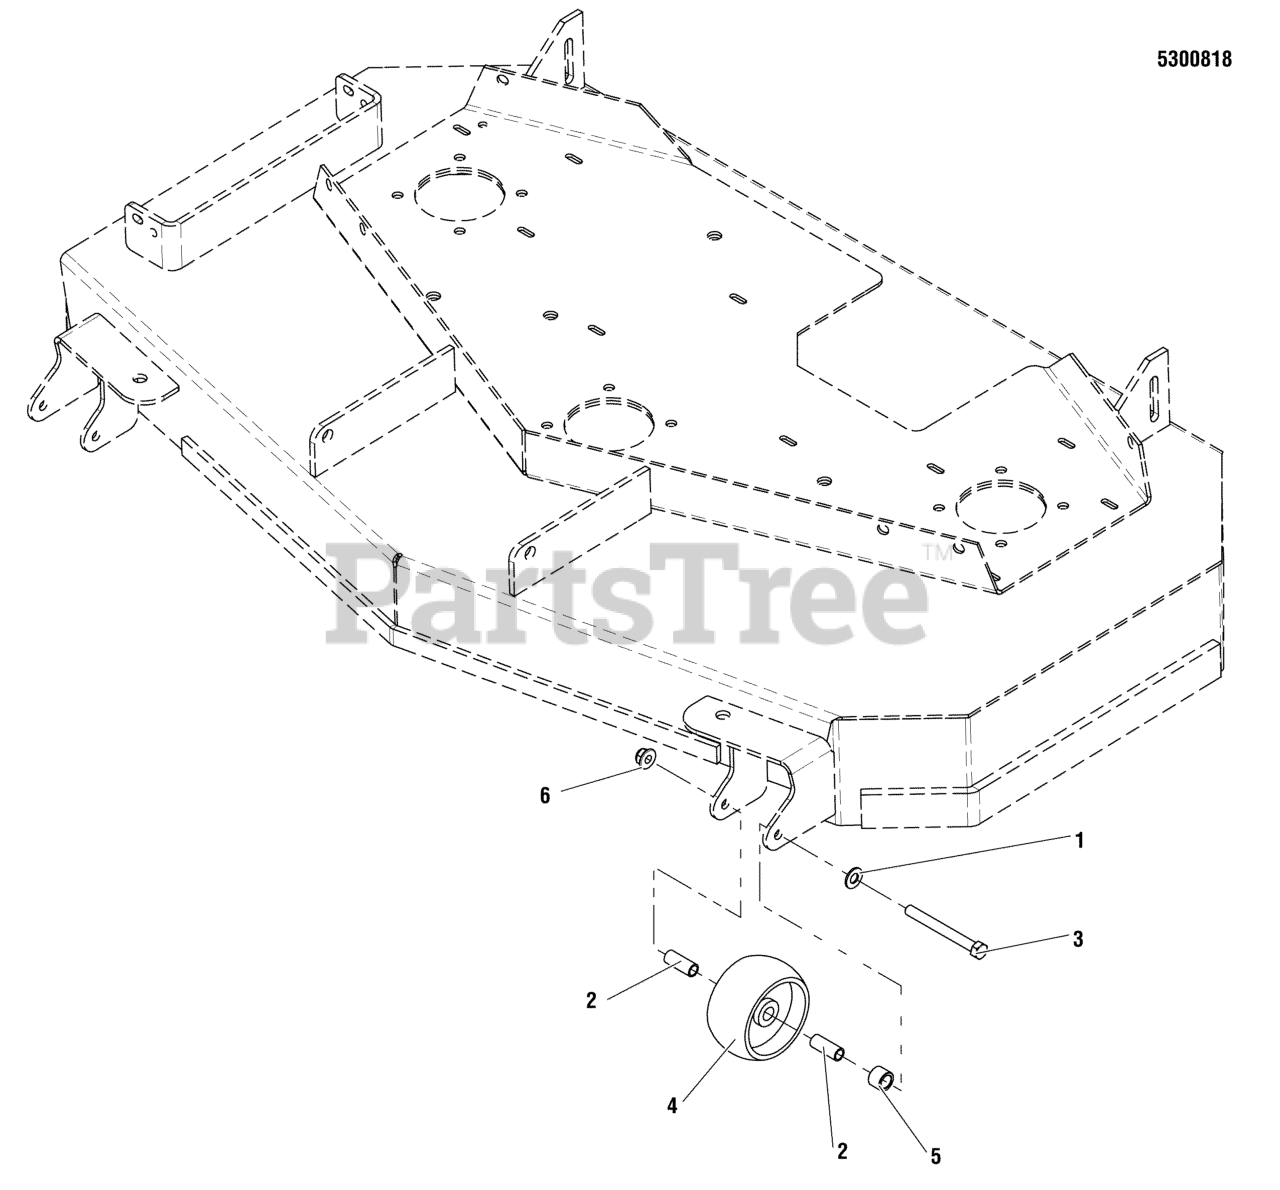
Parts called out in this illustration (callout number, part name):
1	WASHER, 3/8 SAE
2	SPACER, .38 X .50 X 1.25, CZ
3	BOLT, 3/8-16 X 3-1/2" GD5 CZ
4	WHEEL- 2.00 WIDE 3.88 DIA 0.531ID POLY
5	SPACER, .51 X .75 X .56
6	NUT, 3/8-16 HEX NYLOCK FLANGE
